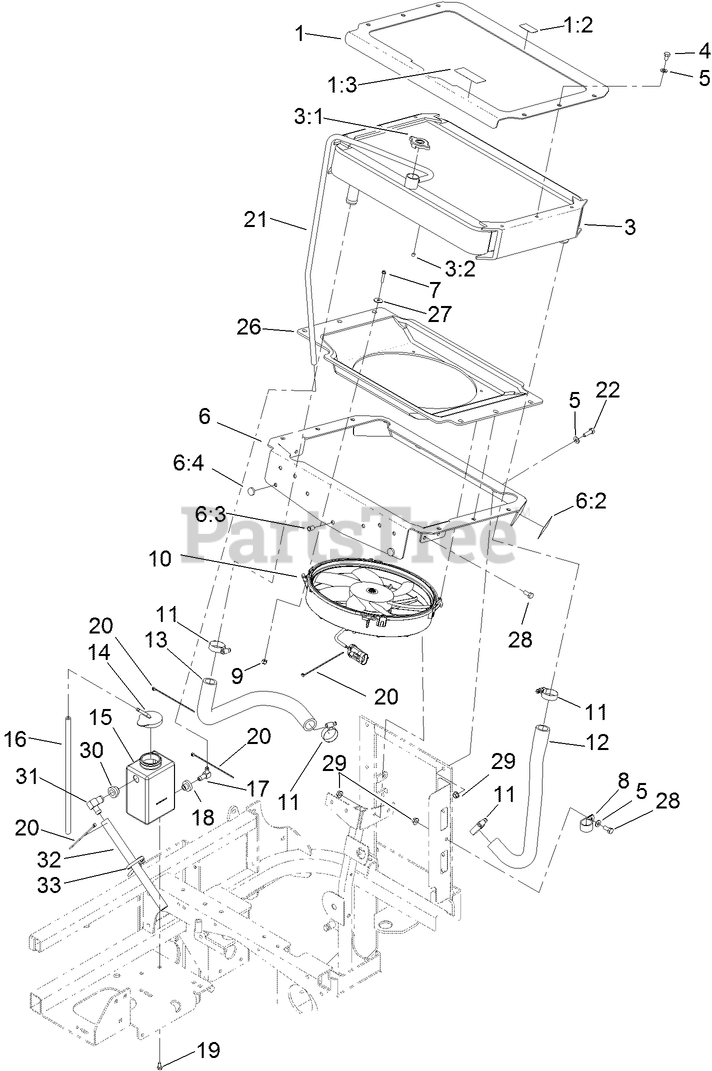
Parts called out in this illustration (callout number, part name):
1	TOP RADIATOR PLATE ASM
1:2	DECAL-SURFACE, HOT
1:3	DECAL-ANTIFREEZE
3	RADIATOR ASM
3:1	CAP-RADIATOR
3:2	PLUG-PIPE
4	SCREW-HH
5	WASHER-PLAIN
6	BOTTOM RAD PLATE ASM
6:2	DECAL-FAN, RADIATOR
6:3	NUT-CLINCH
6:4	BUMPER
8	CLIP-LOOM
9	NUT-LOCK, HH
10	FAN-HI PERFORMANCE
12	HOSE-RADIATOR, LH
13	HOSE-RADIATOR, RH
14	CAP-TANK, OVERFLOW
15	TANK-OVERFLOW
16	HOSE-LINE, FUEL
19	SCREW-HH
20	TIE-CABLE
21	HOSE-OVERFLOW
22	SCREW-HH
26	SHROUD
27	WASHER
28	SCREW-HH
29	NUT-HF
31	FITTING-ELBOW
32	HOSE-OVERFLOW
33	TIE-PLASTIC
